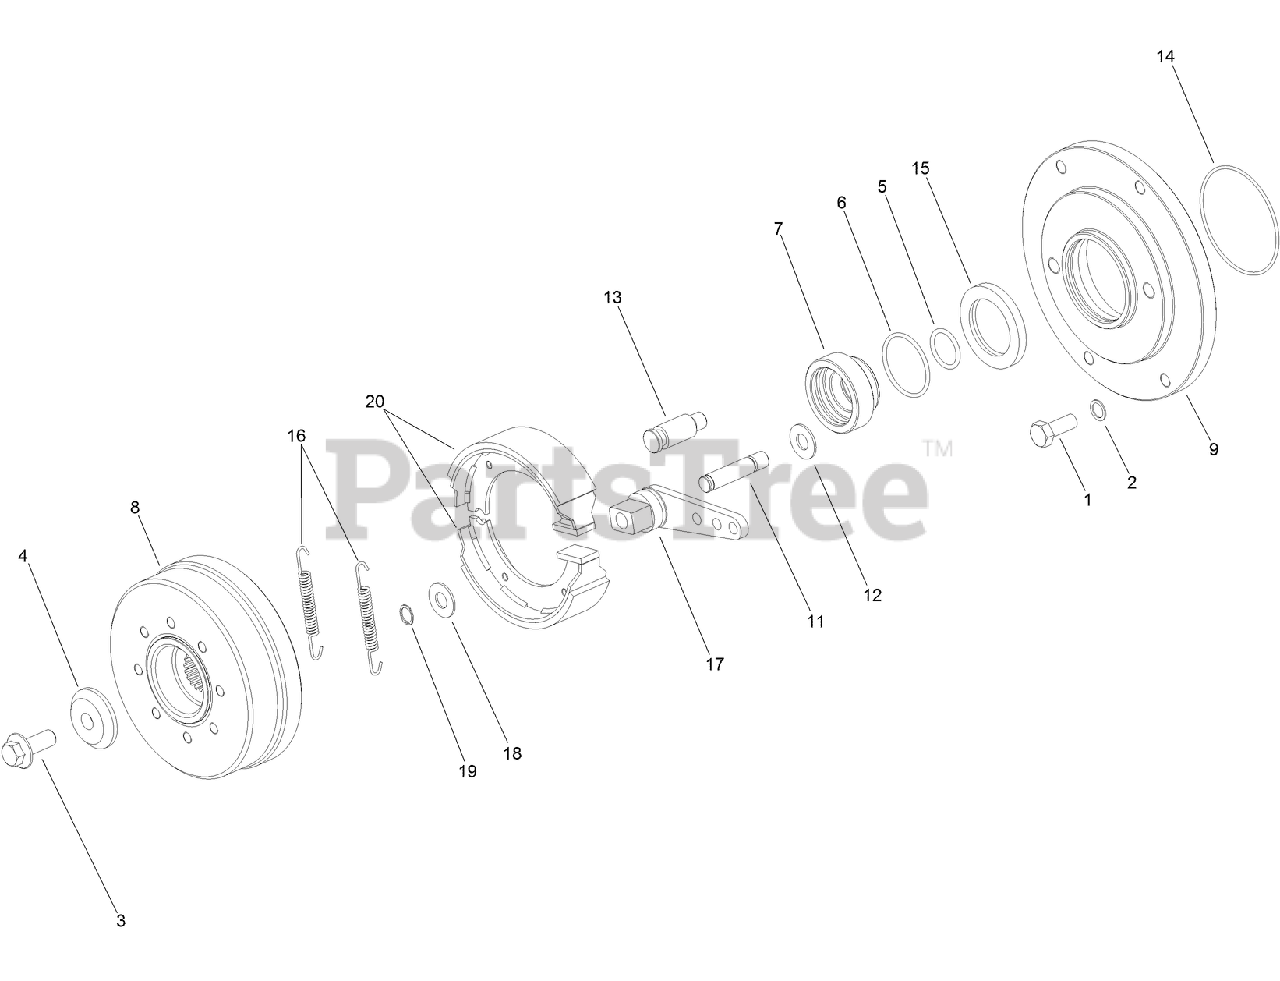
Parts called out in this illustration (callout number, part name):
2	WASHER-SCHNORR
3	SCREW-FLANGED
4	WASHER-PINION
5	O-RING
6	O-RING
7	SEAL-HOUSING
8	DRUM-BRAKE
9	FLANGE-BRAKE
11	PIVOT-LEVER, BRAKE
12	WASHER-AXIAL
13	SHAFT-PIVOT, BRAKE
14	O-RING
15	SEAL-OIL
16	SPRING-BRAKE
17	LEVER-BRAKE
18	WASHER-LEVER, BRAKE
19	RING-SNAP
20	SHOE-BRAKE
